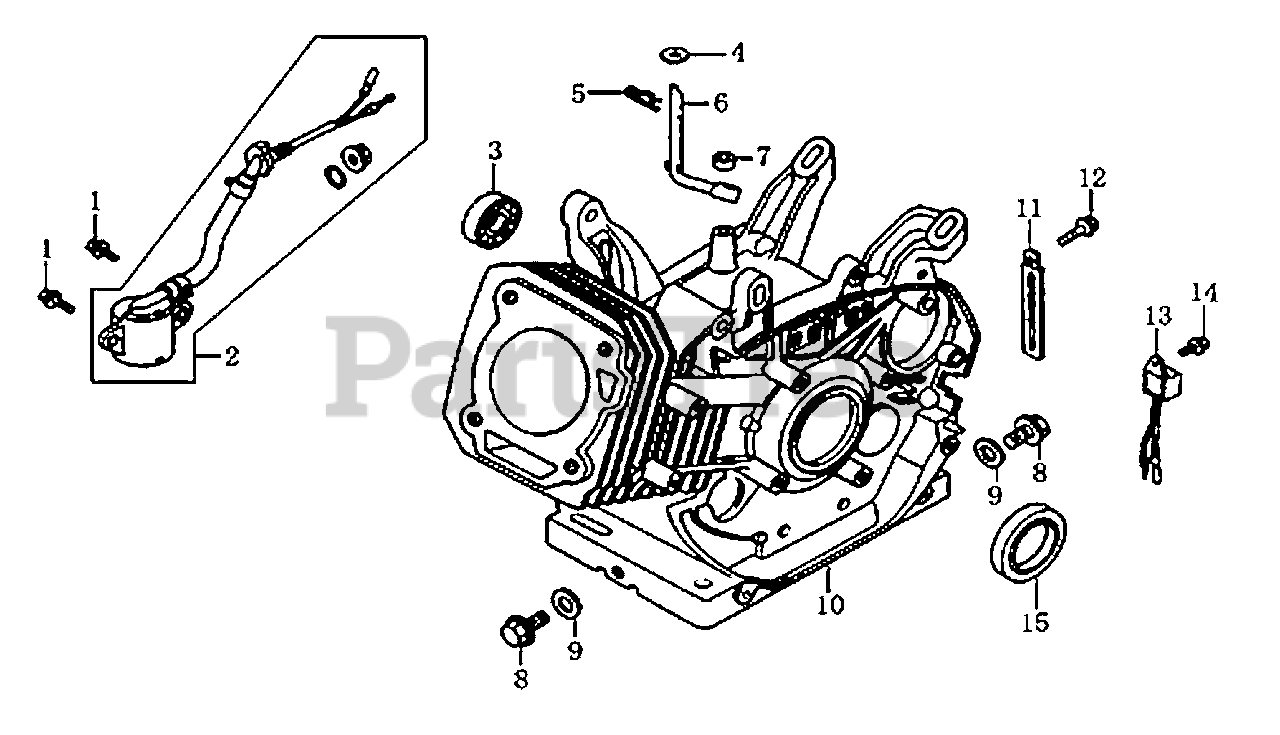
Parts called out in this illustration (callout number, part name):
1	BOLT' FLANGE' 6×14
2	SWITCH ASSY.' OIL LEVEL
3	BEARING' RADIAL BALL' 6202
4	WASHER'8*16*1.2
5	PIN' LOCK' 10MM
6	SHAFT' GOVERNOR ARM
7	OIL SEAL' f8×f14×4
8	BOLT' DRAIN PLUG
9	WASHER' DRAIN PLUG
10	CRANKCASE
12	BOLT' FLANGE' M6×12
13	ALERT UNIT'OIL
14	BOLT' FLANGE' M6×12
